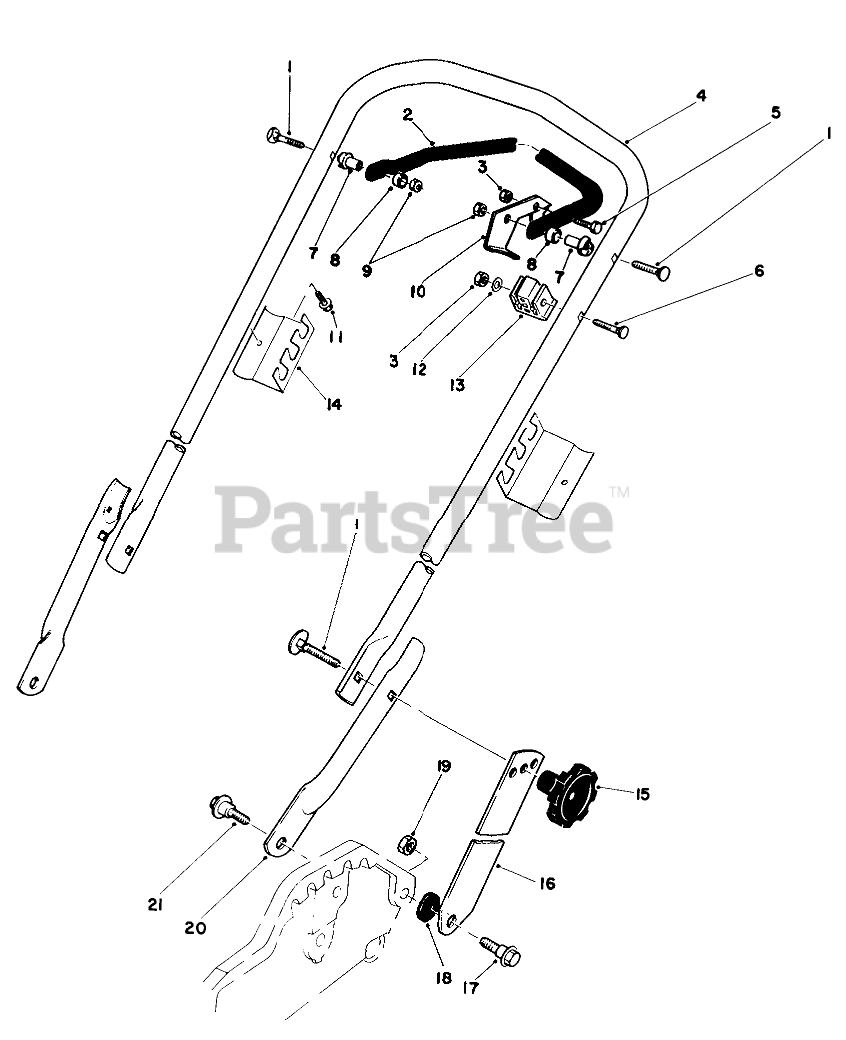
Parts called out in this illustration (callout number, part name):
1	5/16-18 X 2 HNDLE SCREW
2	CONTROL BAR
3	NUT-LOCK, NI
4	Handle-Upper
5	SCREW-HH
6	SCREW-HANDLE
7	SPACER-SUPPORT
8	SPACER-NYLON
9	NUT-LOCK, NI
10	Lever-Control
11	SCREW-HWHTF
12	WASHER-FLAT
13	SUPPORT-CABLE
14	Bag Support
16	Handle Latch
17	SCREW-SHOULDER
18	SPACER
19	NUT-LOCK, NI
20	Hand-Lower
21	SCREW-SHOULDER
